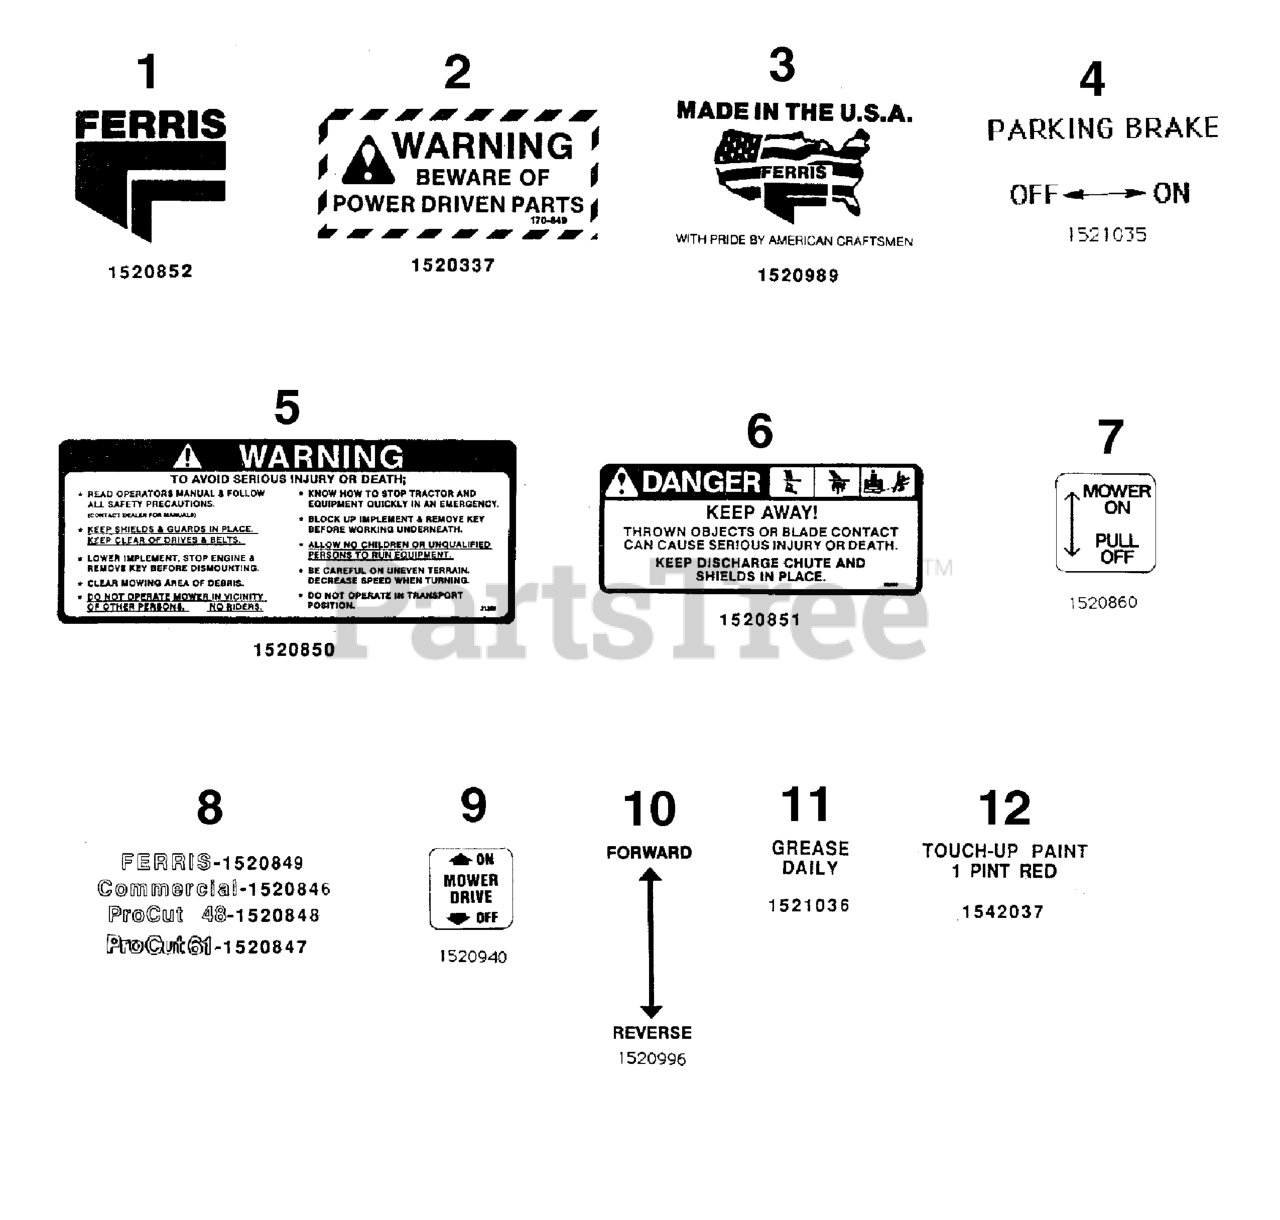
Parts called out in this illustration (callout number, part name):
1	DECAL, Ferris Logo, 10-3/4"
2	DECAL, Warning
3	DECAL, Made In The USA
4	DECAL, Parking Brake
5	DECAL, WARNING Operation
6	DECAL, DANGER DO NOT OPERATE W/O DEFLECT
7	DECAL, Mower On / Off
8	DECAL, FERRIS TEXT & LOGO
8	DECAL, Commercial
8	DECAL, Word, PROCUT 48
8	DECAL, Word, PROCUT 61
9	DECAL, Mower Drive On / Off
10	DECAL, Direction Control
11	DECAL, Grease Daily
12	DECAL, Touch-Up Paint
